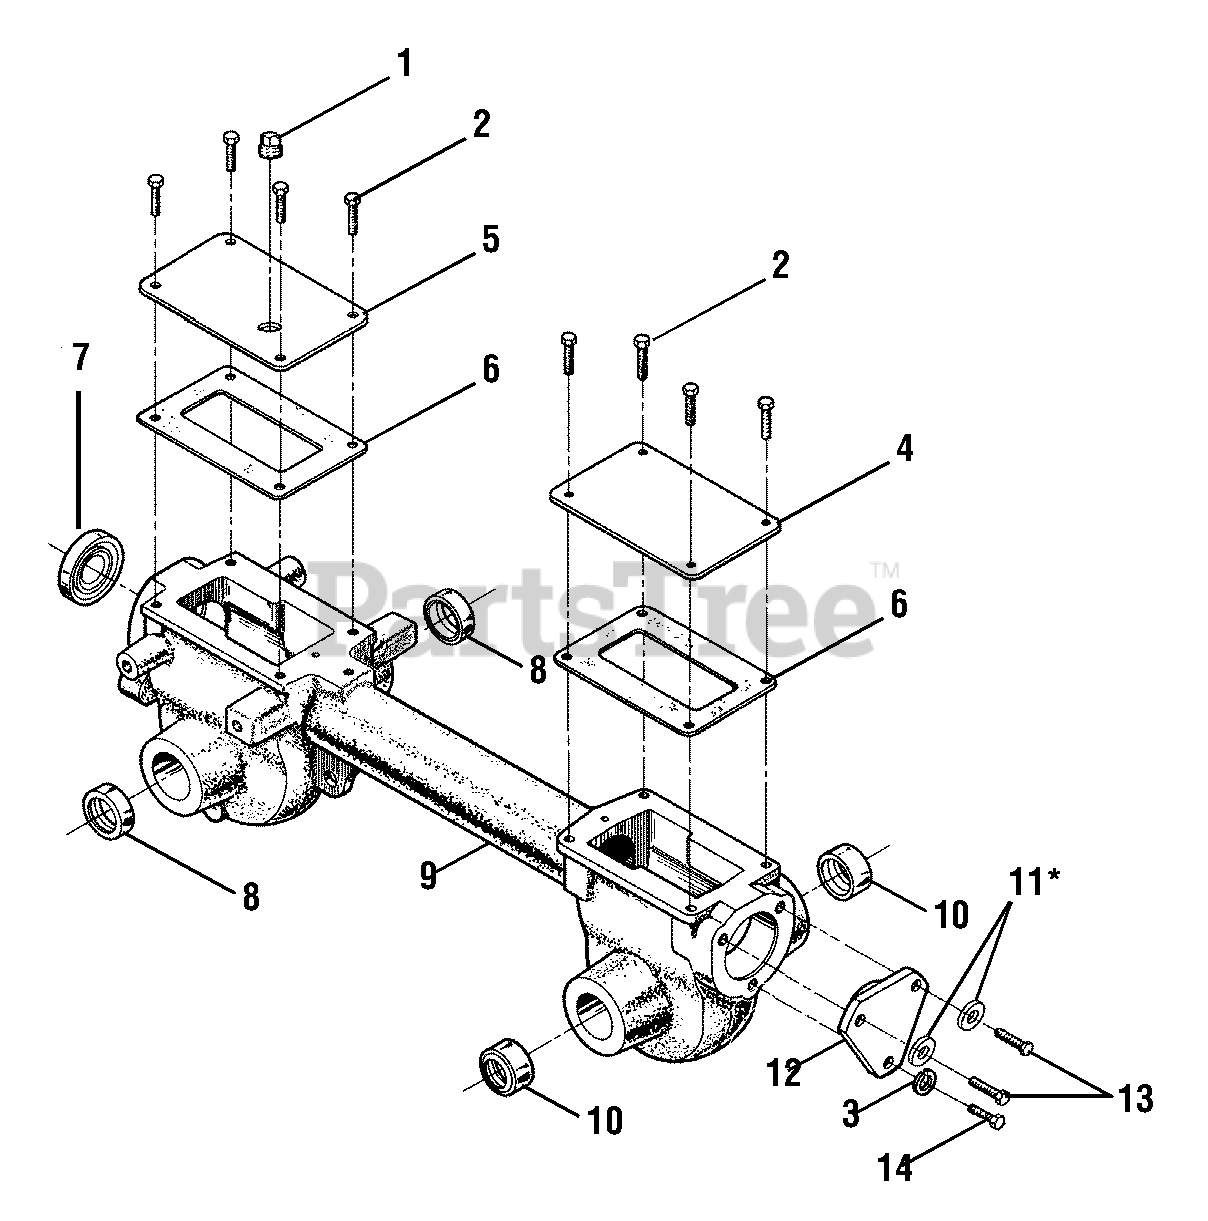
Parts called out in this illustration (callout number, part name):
1	Plug, Transmission Oil Fill
2	Hex Hd. Flange Screw, 5/16-18 x 5/8,Gr. 5
3	Lock Washer, 5/16
4	Rear Cover, Transmission
5	Front Cover, Transmission
6	Gasket, Housing Cover
7	Oil Seal, Drive Shaft
8	Oil Seal, Wheel Shaft
9	Transmission Housing Assembly
10	Oil Seal, Tine Shaft
11	Washer, Flat, .344 x .750 x .120
12	Rear Bearing Cap
13	Hex Hd. Flange Screw, 5/16-18 x 1
14	Hex Hd. Flange Screw, 5/16-18 x 3/4
